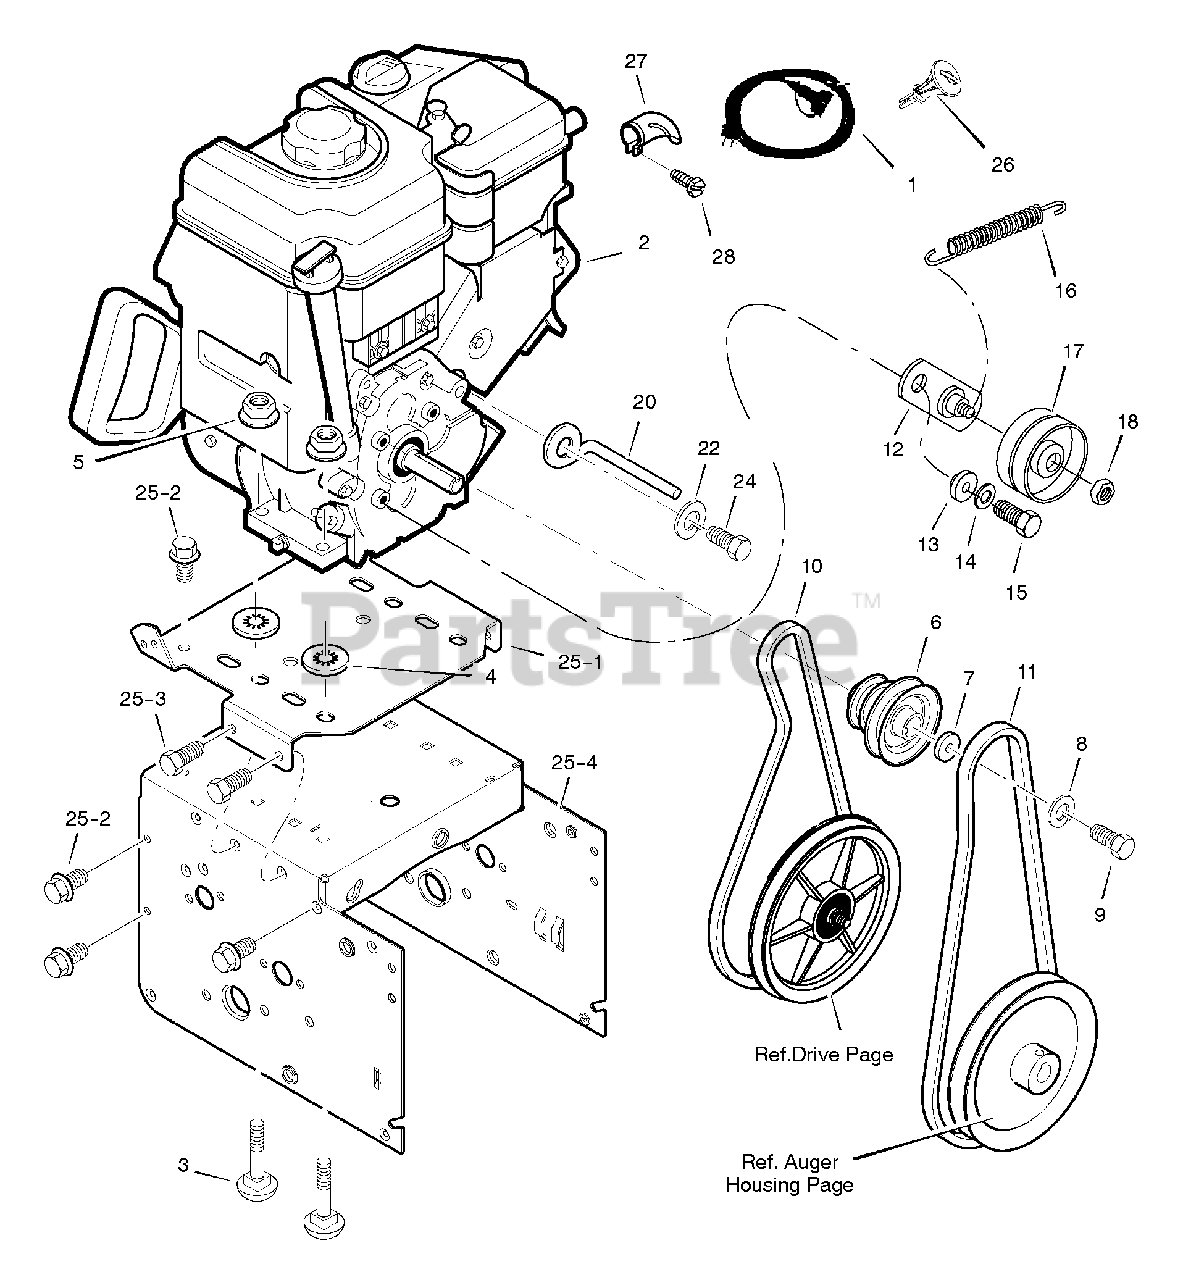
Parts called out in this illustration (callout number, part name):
1	CORD, STARTER
2	ENGINE
3	BOLT, CARRIAGE
4	RETAINER, PUSH
5	NUT
6	PULLEY, ENGINE
7	WASHER
8	WASHER
9	SCREW
10	BELT, DRIVE V 4L
11	BELT, AUGER V 3L
12	BRACKET ASSEMBLY, IDLER
13	BUSHING, IDLER BRACKET
14	WASHER, SPLIT
15	SCREW 5/16-24 X .75
16	SPRING, IDLER TRACTION DRIVE
17	PULLEY, IDLER
18	NUT, JAM 3/8-16
20	GUIDE, ROD BELT
22	WASHER
25	FRAME ASSEMBLY
25-1	PLATE, ENGINE
25-2	SCREW
25-3	SCREW
25-4	MOTOR BOX
26	KEY, BRIGGS ENGINE
27	DEFLECTOR, MUFFLER
